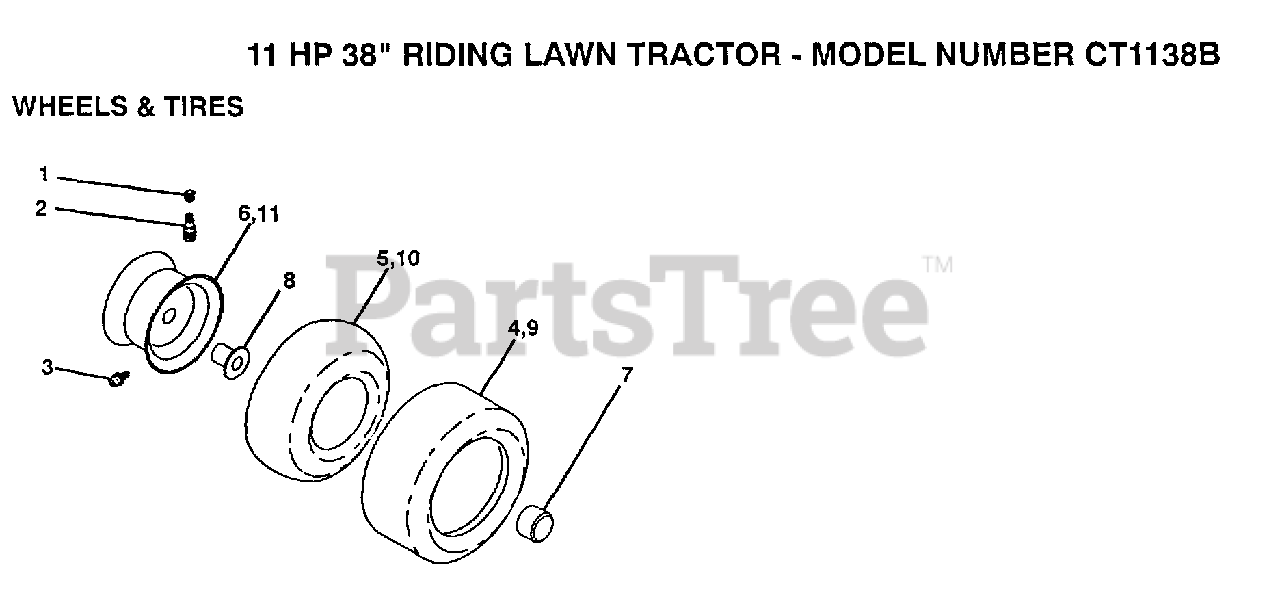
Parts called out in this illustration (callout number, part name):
1	VALVE CAP
2	VALVE STEM LT
3	FITTING LT
5	TUBE.5.3/4.5/6
7	HUB CAP
8	"FLANGE, BEARING"
10	TUBE.18X9.5-8
